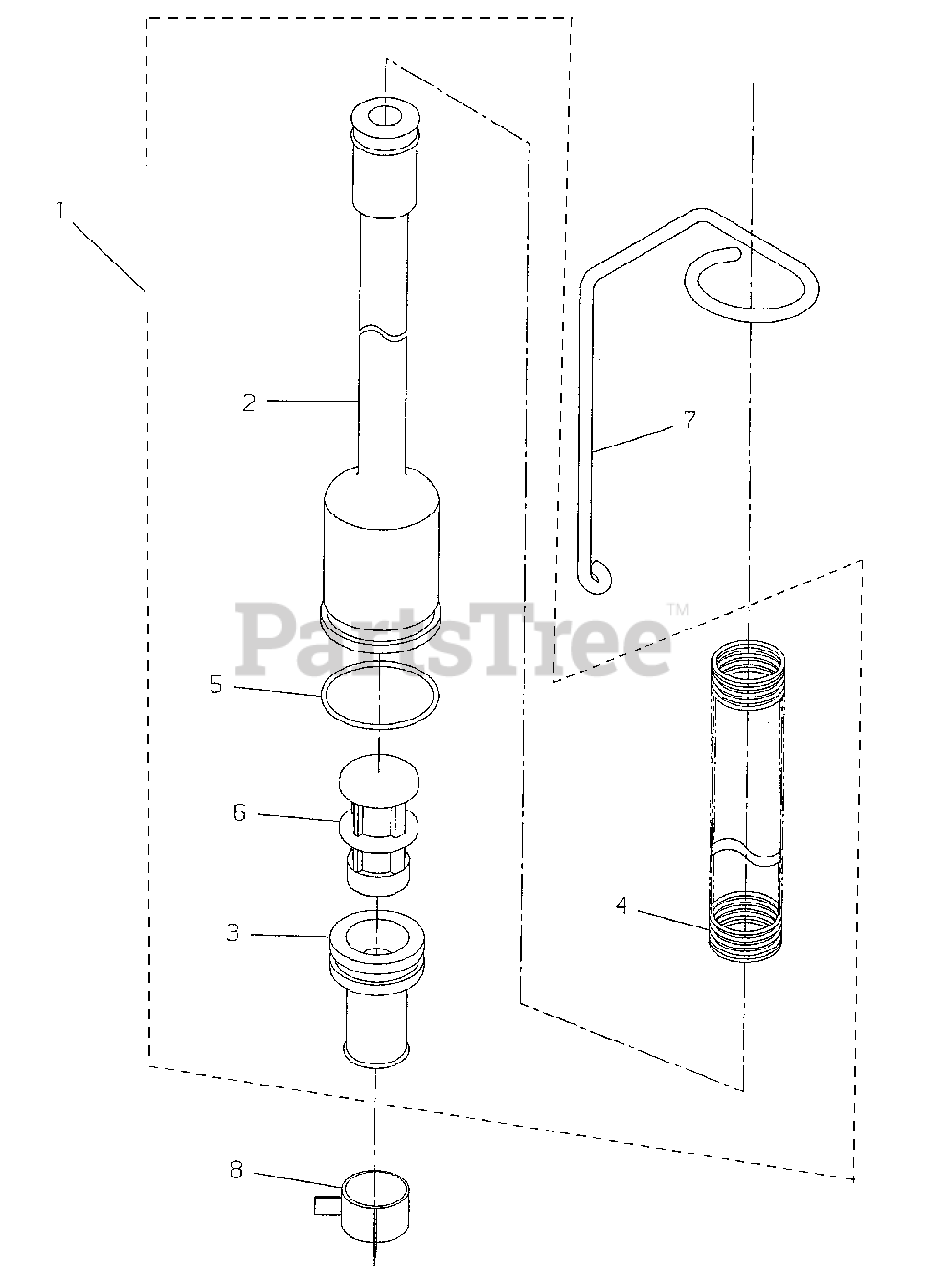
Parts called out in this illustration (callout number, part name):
1	FILTER ASSY, FUEL
2	PIPE, FUEL
3	CONNECTOR, PIPE
5	CLIP
6	BODY, FUEL FILTER
7	HOLDER
8	CLAMP, HOSE
